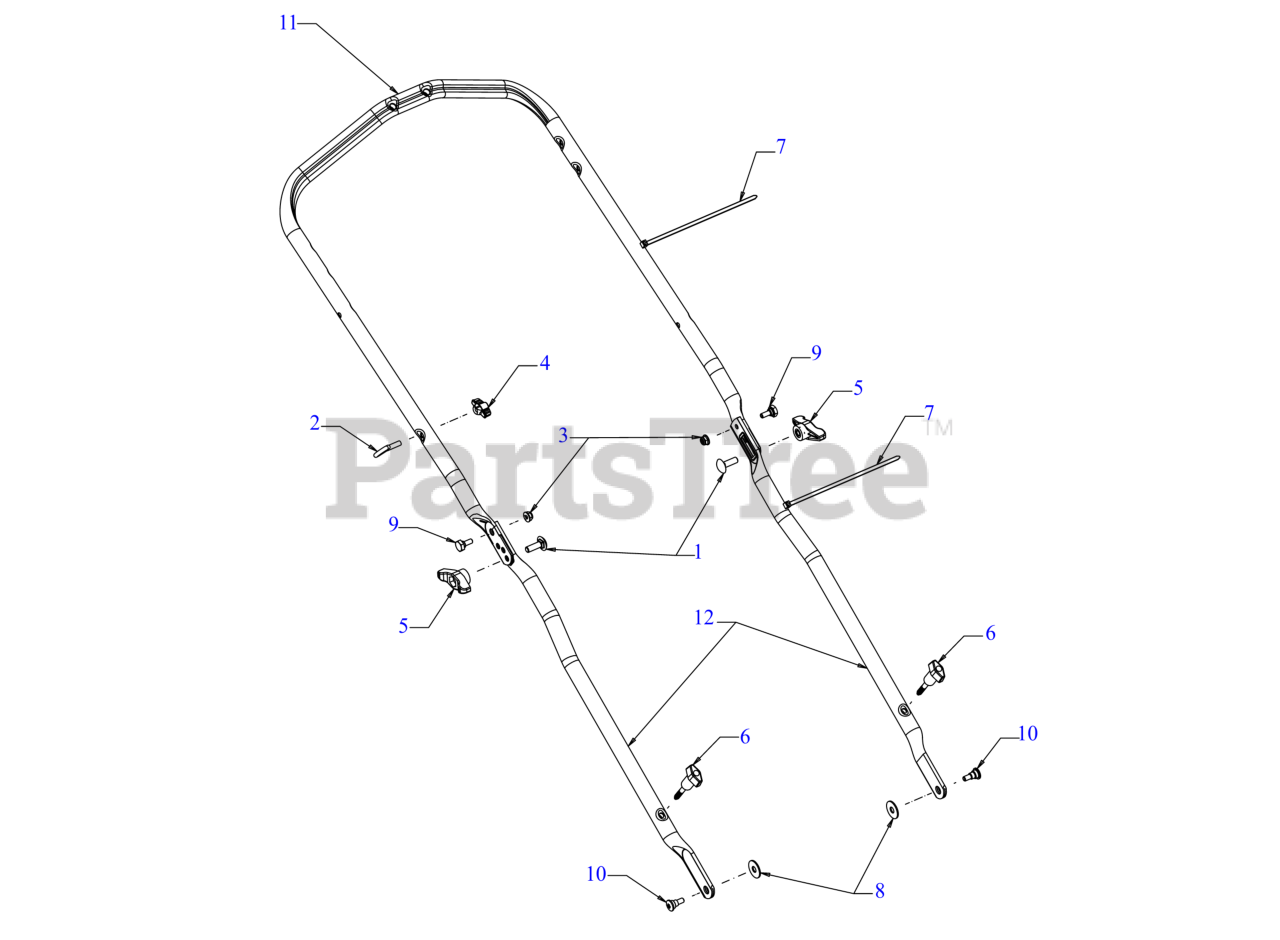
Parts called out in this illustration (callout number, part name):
1	SCREW 5/16-18 x 1.00 GR5
2	EYEBOLT 1/4-20
3	FLANGE LOCK NUT
4	HANDLE KNOB
5	WING KNOB 5/16-18
6	WING KNOB 1/4-20
7	7" CABLE TIE
8	FLAT WASHER 344X1.00
9	SHOULDER SCREW
10	SHOULDER SCREW .450X .188X 1/4-20
11	UPPER HANDLE (SQUEEZE GRIP XL) (POWDER BLACK)
12	LOWER HANDLE (EZ FOLD) (POWDER BLACK)
